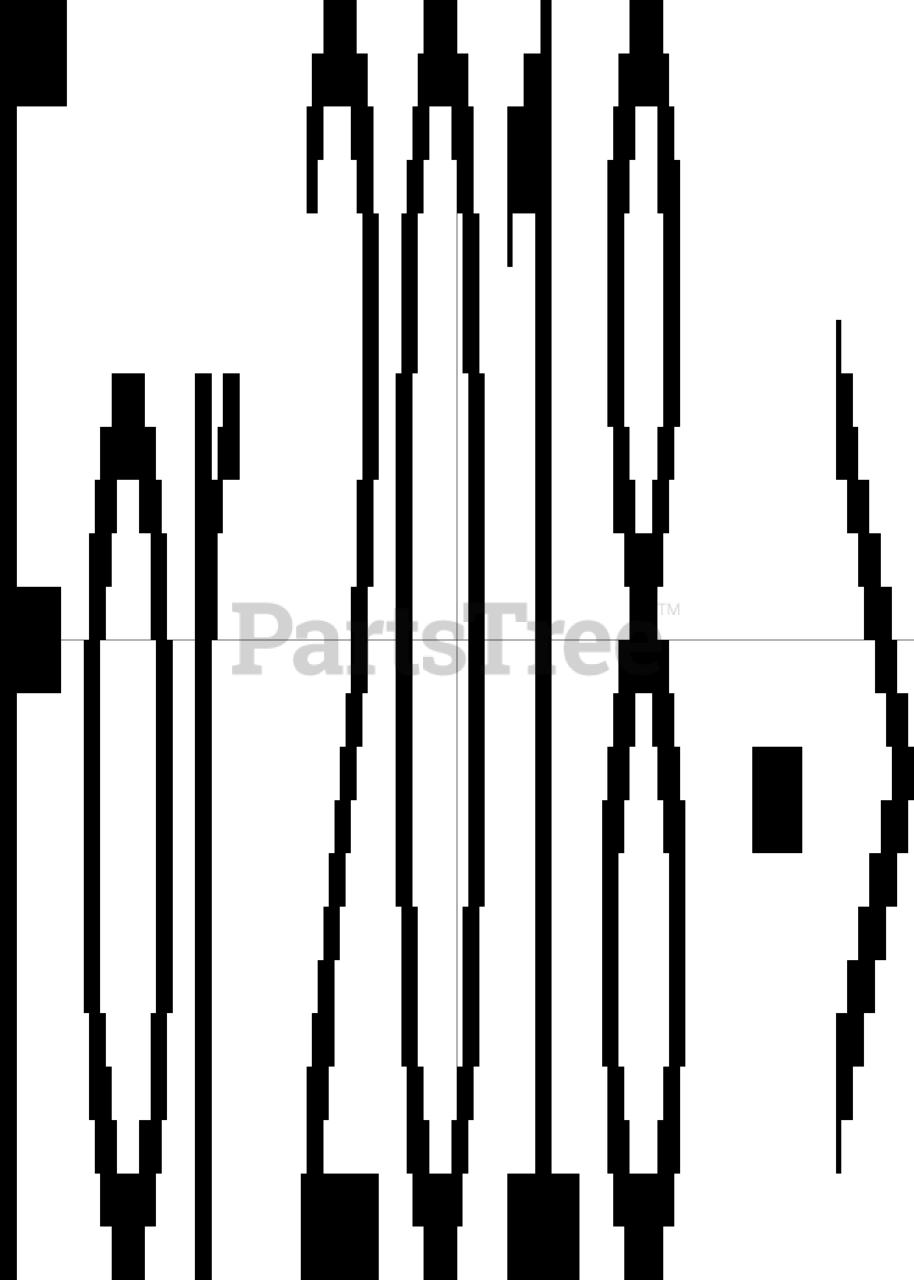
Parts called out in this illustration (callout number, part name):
6	LIFTING ARM LINK
11	BEARING FLANGE
21	CONNECTION ROD
24	RETAINING RING
25	CONNECTION ROD
